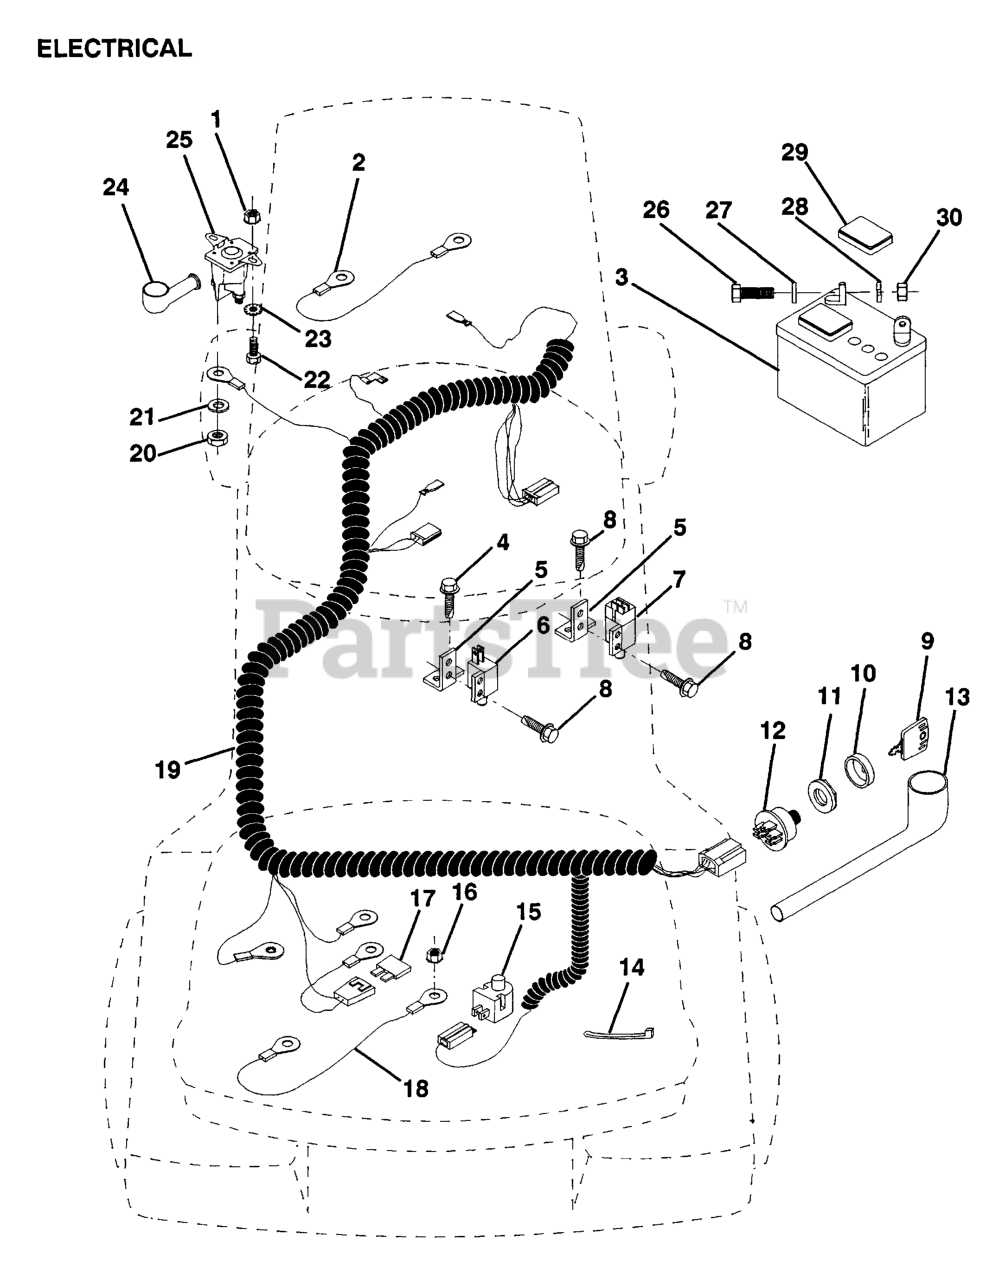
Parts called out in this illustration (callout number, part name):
1	NUT
2	CABLE ASSY-BATTERY
3	BATTERY
3	BATTERY - DRY
4	Screw - Hex Washer Hd. Tapping 10 - 16 x 5/8
5	BRACKET LT
6	SWITCH-INTER. GT
7	SWITCH INTERLOCKT
9	KEY.MOLDED.GENERIC
10	COVER KEY IGNITIO
11	NUT IGNITION
12	SWITCH
13	COVER IGNITION SW
14	TIE GUIDE
15	RP.SWITCH.PLUNGER.NC.GRAY
16	LOCKNUT
20	NUT.CROWNLOCK.1/4
21	LOCKWASHER
22	BOLT.HEX.1/4.X.3/4.DICHROMATE
23	LOCKWASHER
24	TERMINAL COVER
25	SOLENOID KIT
26	BOLT.HEX.1/4.X.3/4.DICHROMATE
28	LOCKWASHER
29	CAP BATTERY NLA
30	NUT
